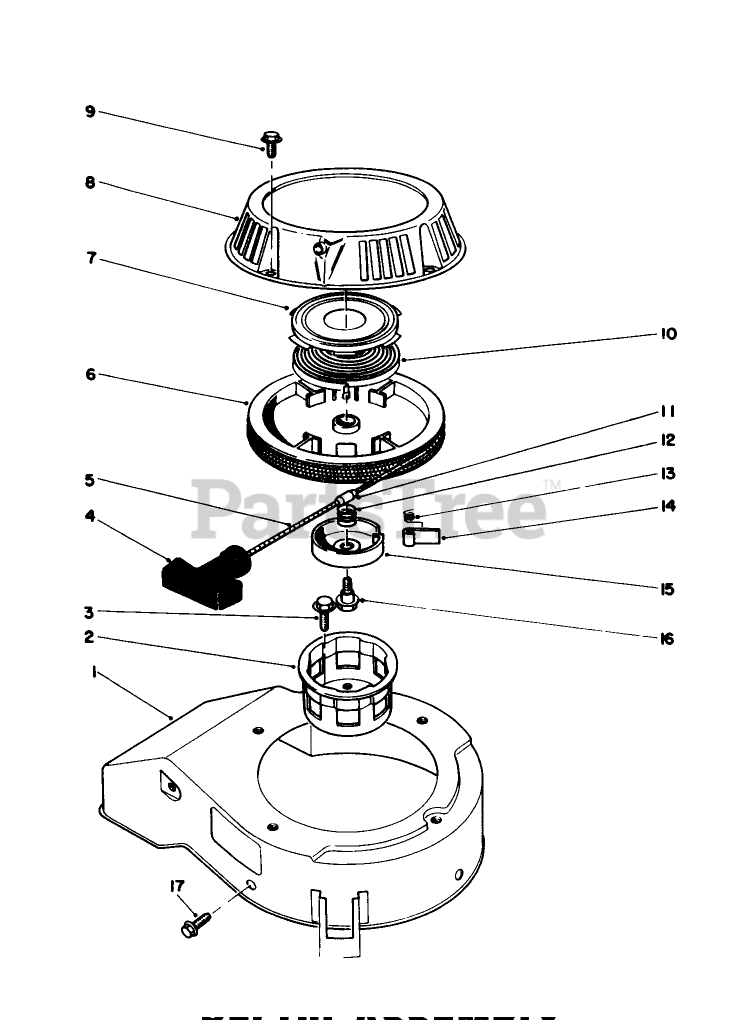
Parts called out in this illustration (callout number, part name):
2	CUP - STARTER
4	HANDLE-RECOIL
7	Retainer-Recoil Spring
9	SCREW-HHF
10	Spring-Recoil
12	SPRING
13	SPRING
15	RETAINER
